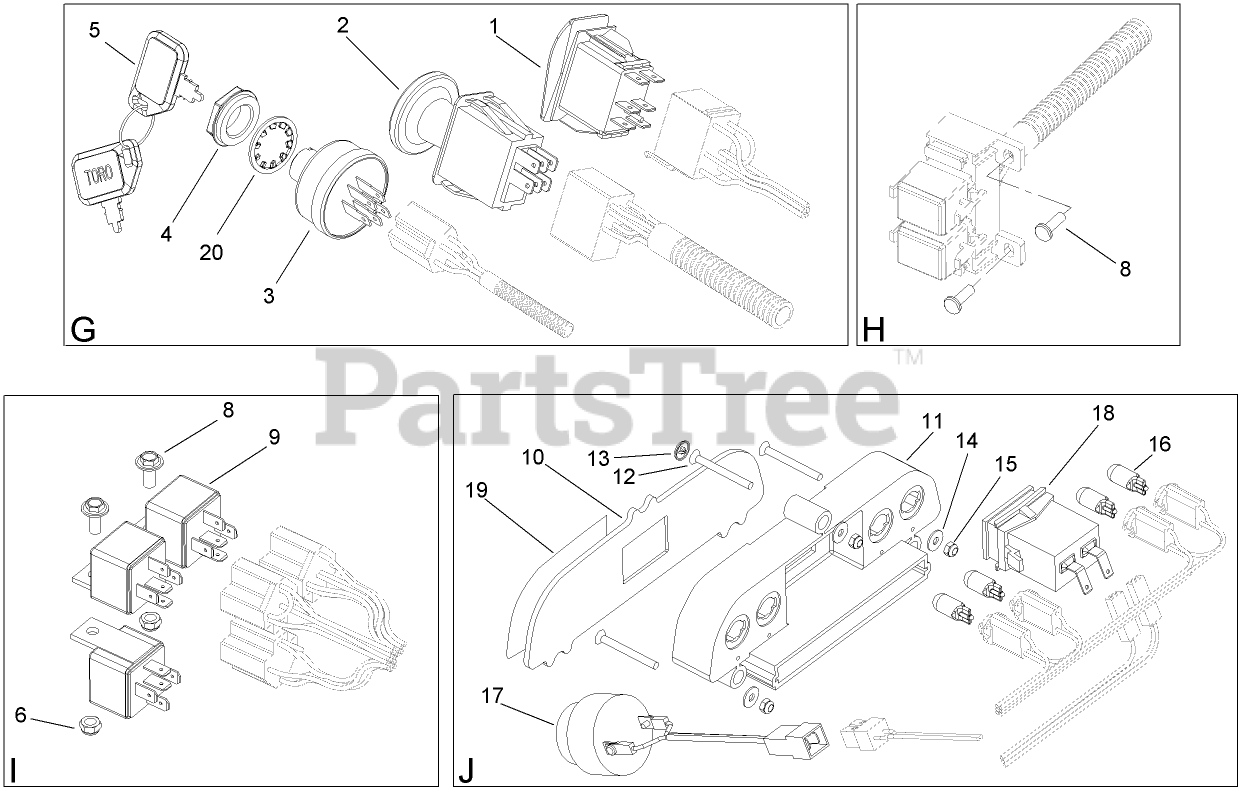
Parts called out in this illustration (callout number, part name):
1	SWITCH-CRUISE
2	SWITCH-PTO,ON-ON-NONE
3	SWITCH-IGNITION
4	NUT-HH
5	KEY-IGNITION
6	NUT-LOCK
8	SCREW-HEX
10	LENS-DASH
11	HOUSING-LIGHT, INDICATOR
13	CAP-SCREW
14	WASHER
15	NUT-HEX
17	BUZZER
18	HOURMETER
19	DECAL-DASH
20	WASHER-LOCK
